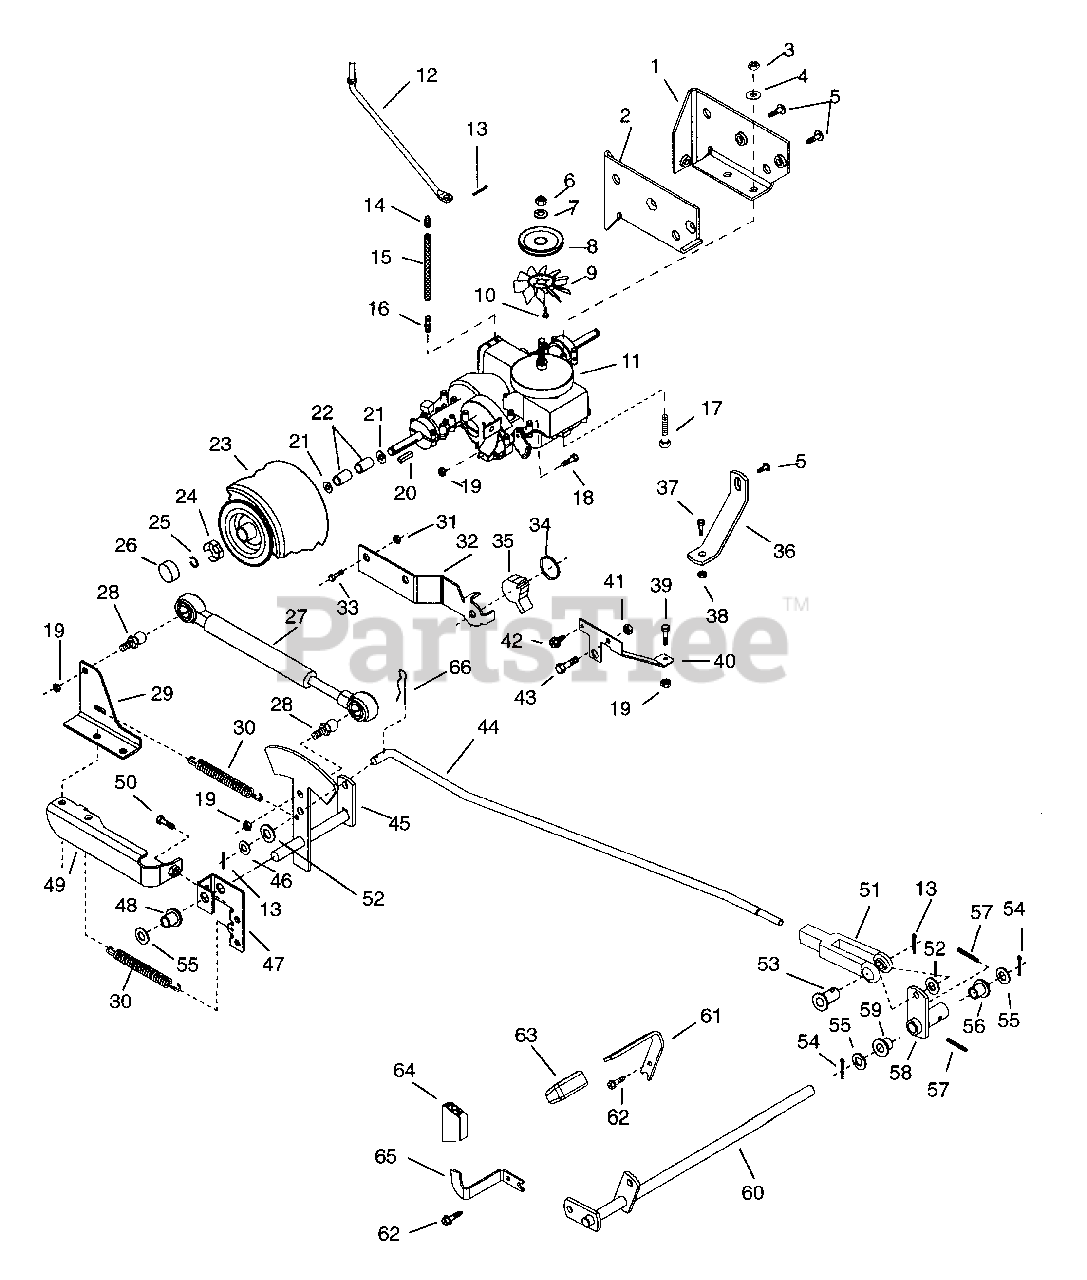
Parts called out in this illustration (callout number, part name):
1	MOUNT - TRANS. LH
2	MOUNT - TRANS. RH
3	NUT-LK-TOP .312-18 GR C PL
4	WSHR-FL-STL .328X.875X.062 PL
5	SCR-TAP .375-16X.75 HWH PL TR
6	NUT-JAM .50-20 PL
7	WSHR-LK .50 REG.
8	SHEAVE - TRANSAXLE
10	SCR-TAP 10-32X.62 HWH PL T
11	TRANSAXLE- HYDRO #325-0750
12	ROD - TRANS. DISCONNECT
13	PIN-COTR .09X.75 PL
14	CAP-VENT .50
15	HOSE- VENT .50ID X 7.50LONG
16	FTG-STR .50 O-RING
17	BLT-HEX .31-18X2.50 PL GR5
18	BLT-HEX .31-18X.75 PL GR2
19	NUT-LK .312-18 GR A PL
20	KEY-SQ .188X2.0X.188 SAE 8630
21	WSHR-FL-STL .755X1.375X.062 PL
22	BSHG-SLV .750X1.125X1.062
23	T/WHL ASSY 20X8.00-8
23	RIM
23	TIRE 20X10-8 2P TS TL
24	SPINDLE CUP
25	RG-RTNG-EXT .750X.050
26	HUB CAP
27	DAMPER - HYDRAULIC
28	STUD- BALL
29	ANCHOR - SPRING - TOP
30	SG-TENS .085X.60X5.13 WLD8.3
31	NUT-LK-CTR .375-16 GR A PL
32	MOUNT - MAGNET
33	BLT-HEX .38-16X.50 PL GR5
34	O-RING 1.125X1.375X.125
35	MAGNET
36	STRAP - TORQUE L.H.
37	CHOKE CONTROL
38	NUT-LK-NYL.312-18 PL
39	BLT-HEX .31-18X2.25 PL GR5
40	STRAP - TORQUE R.H.
41	NUT-LK TOP .375-16 GR C YWZC
42	SCR-TAP .312-18X.50 HWH TR BL
43	BLT-HEX .38-16X.75 PL GR5
44	ROD - SHAFT
45	ARM - SHIFT
46	WSHR-FL-STL.406X.812X.065PL
47	PIVOT - REVERSE
48	BSHG-FLG .508X.645X.459X.75 NY
49	ANCHOR - SPRING - BOTTOM
50	BLT-HEX .31-18X1.25 PL GR2
51	SNAP-SWIVEL .625
52	WSHR-FL-STL .390X.750X.125 PL
53	PIN-CLEV .312X.822 HDND PL
54	PIN-COTR .12X1.0 PL
55	WSHR-FL-STL .520X.827X.062 YZ
56	BSHG-FLG .515X.750X.745X1.00NY
57	PIN-GRV .188X1.25 TP A
58	ARM & HUB
59	BSHG-FLG .502X1X.750
60	SHAFT - PEDAL
61	PEDAL - FORWARD
62	SCR-TAP .375-16X .50 HWH PL TR
63	COVER - PEDAL - FORWARD
64	COVER - PEDAL - REVERSE
65	PEDAL - REVERSE
66	PIN-HAIR INT .08X.18X1.18
